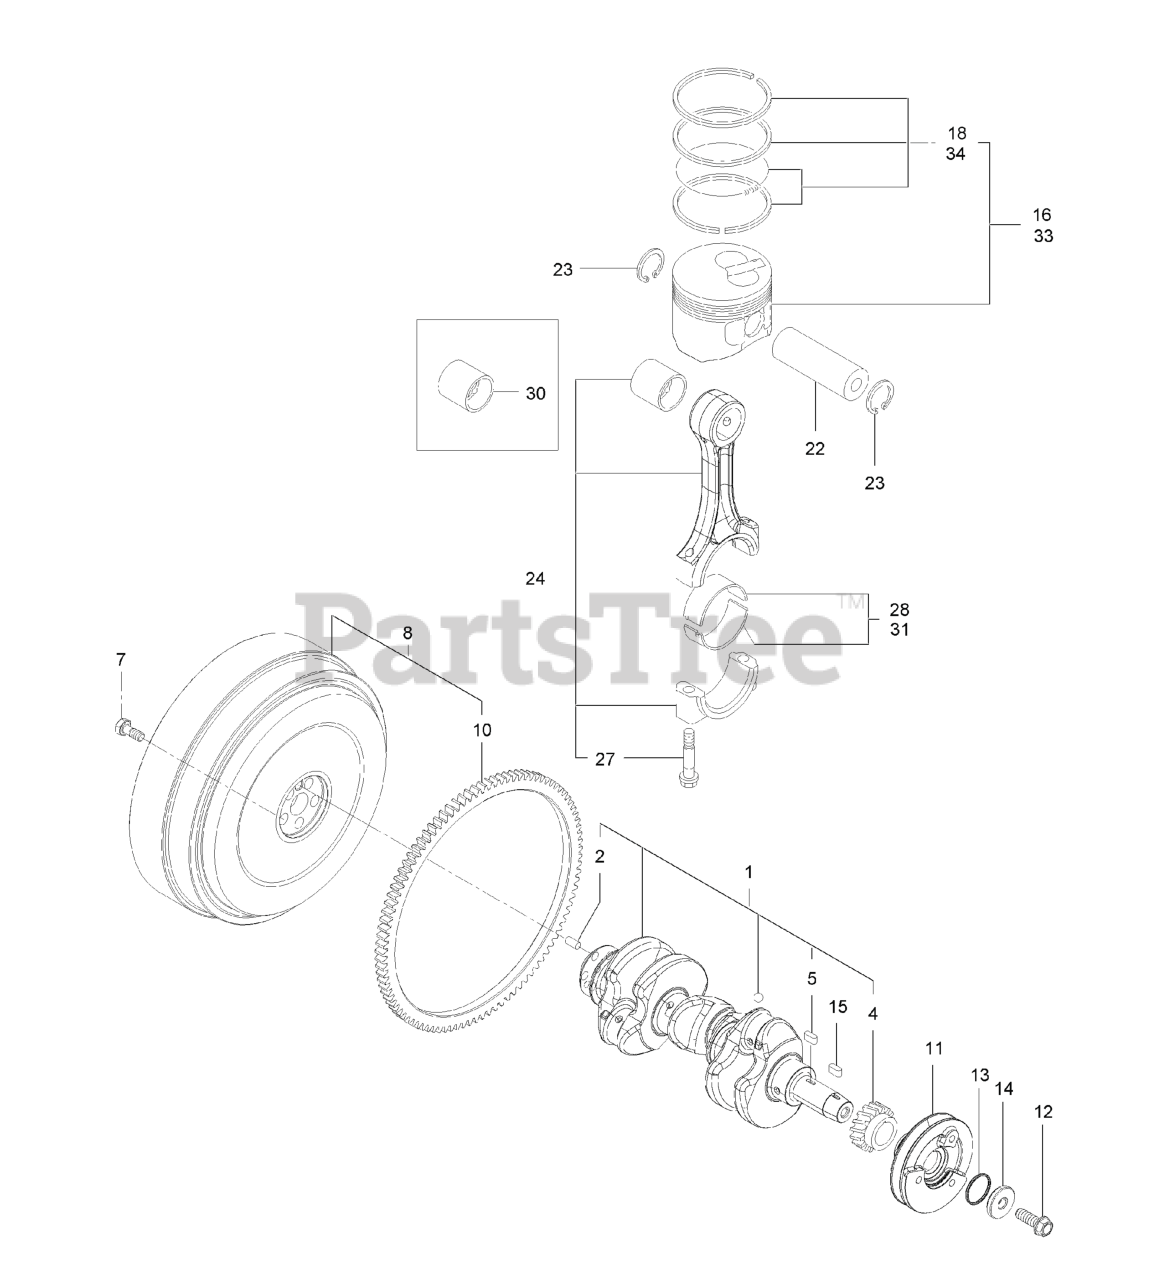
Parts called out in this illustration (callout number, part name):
1	CRANKSHAFT ASM
4	GEAR-CRANKSHAFT
7	BOLT, FLYWHEEL 5
8	FLYWHEEL ASM
10	GEAR-RING
11	V-PULLEY, CRANKSHAFT 1
12	BOLT, FLANGE 12X1.25 1
13	GASKET-WASHER
16	PISTON ASM
18	RING ASM
22	PIN-PISTON
24	ROD ASM-CONNECTING
27	BOLT-CONNECTING ROD
28	BEARING-CRANK PIN
30	BEARING-PISTON PIN
31	BEARING, PIN 0.25
33	PISTON ASM
34	RING ASM
